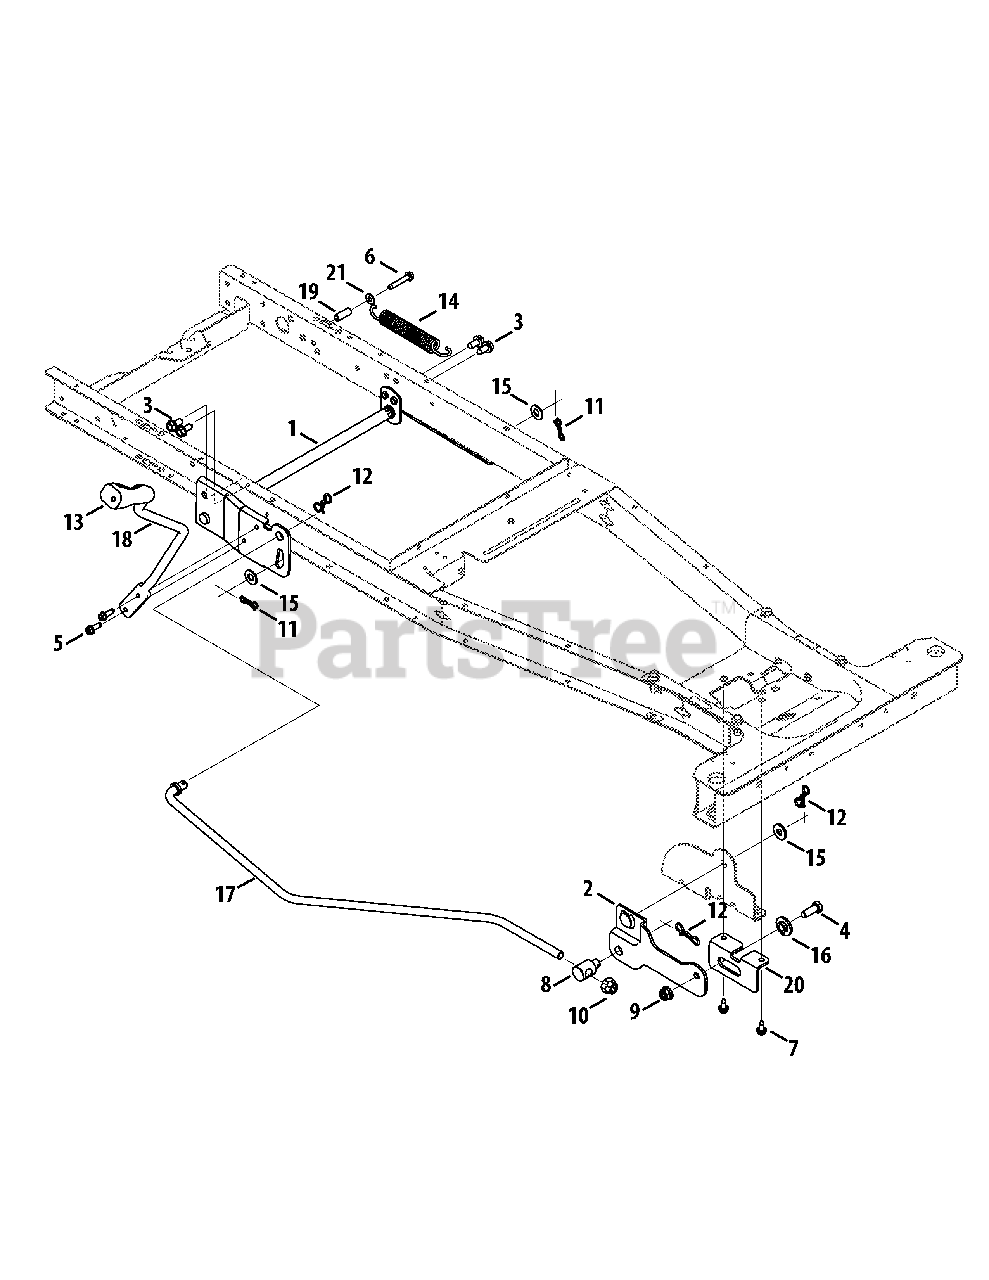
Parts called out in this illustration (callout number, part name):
1	Lift Assembly Shaft
2	Front Hanger Bracket Assembly
3	Tap Screw, 5/16-18 x .750
4	Hex Head Screw 3/8-16 x 1.00
5	Tap Screw 1/4-20, 0.750
6	Tap Screw 1/4-20, 1.50
7	Tap Screw 1/4-20 x .625
8	Ferrule .50 x50
9	Flange Lock Nut 3/8-16
10	Nylon Lock Nut 1/2-13
11	Bow-Tie Cotter Pin
12	Bow-Tie Cotter Pin
13	Grip Handle 1/2
14	Extension Spring .85 OD x 5.915 Lg.
15	Flat Washer .406 x .875 x .059
16	Shoulder Spacer .625 ID x .169
17	Lift Link Rod
18	Deck Lift Rod
19	Spacer .260 x .375 x 1.030 Lg.
20	Front Deck Mounting Bracket
21	Flat Washer .250 x .630 x .052
